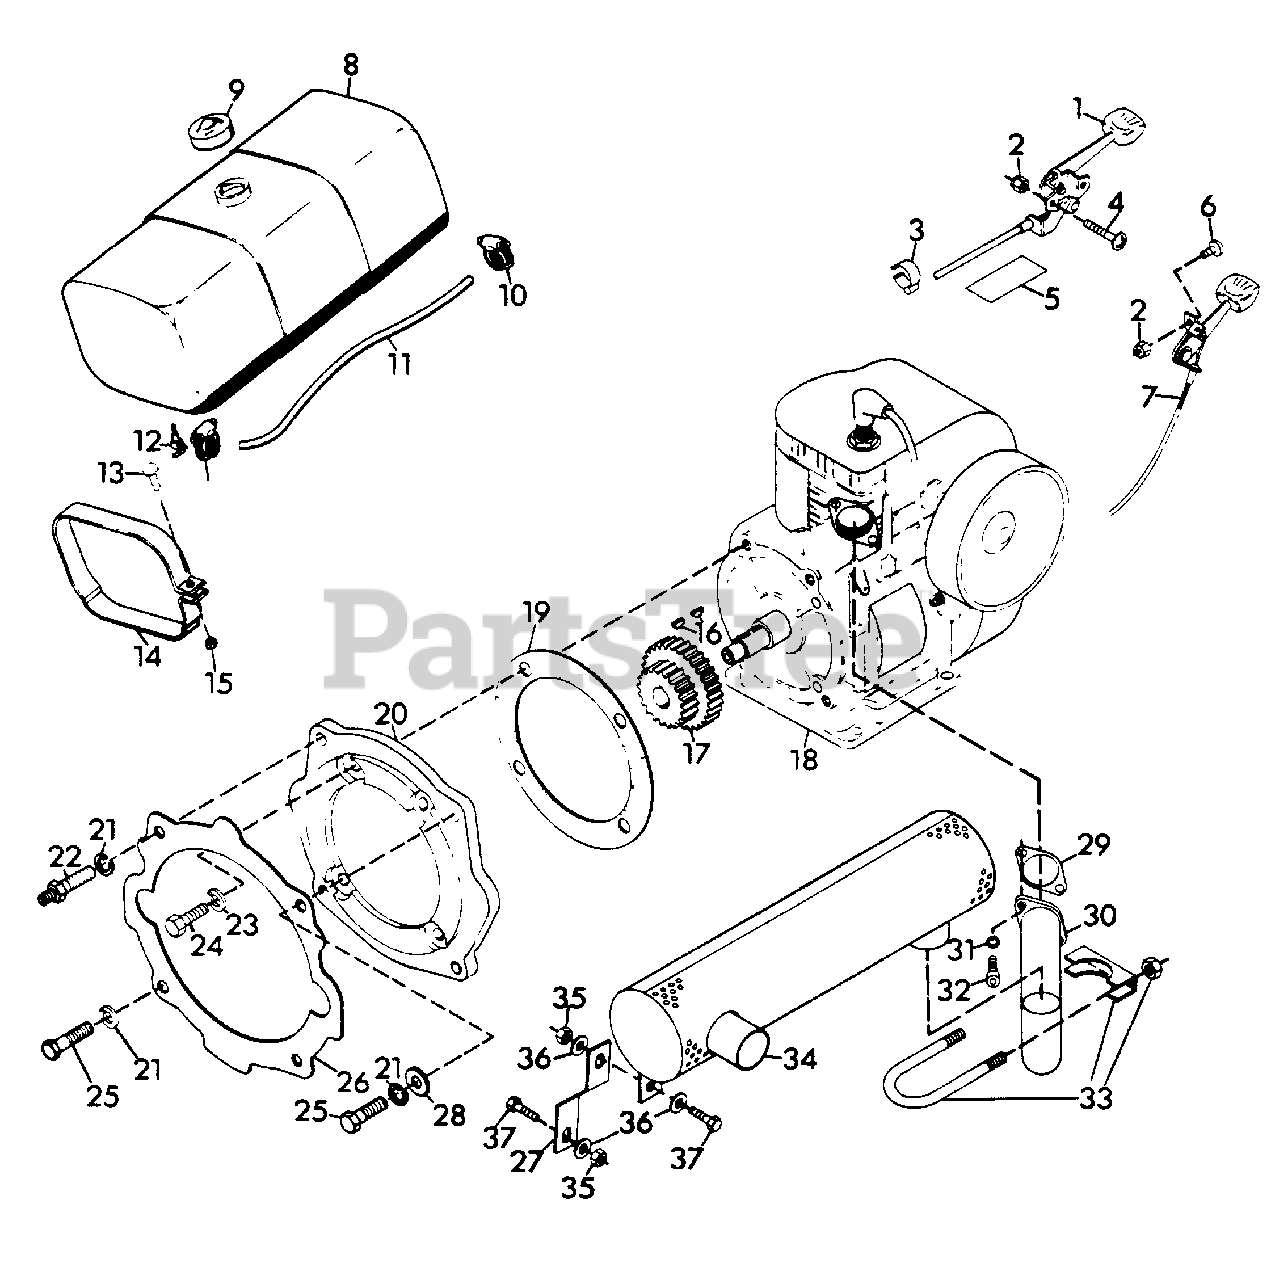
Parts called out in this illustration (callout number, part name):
1	LEVER, THROTTLE CONTROL
2	NUT, LOCK 10-24
3	CLIP, CONDUIT
4	SCREW, MACH. 10-24X1.50 PHD
5	DECAL, THROTTLE
6	SCREW, MACH. 10-24X.50 PHD
7	LEVER, CHOKE CONTROL
8	ASSEMBLY, FUEL TANK
9	CAP, GAS TANK
10	CLAMP, HOSE
11	LINE, FUEL
12	VALVE AND STRAINER
13	BOLT, 1/4-20X1.75 RD.HD.SQ. NECK
14	STRAP, FUEL TANK
15	NUT, LOCK 1/4-20
16	KEY, WOODRUFF 5/32X5/8 HARD #6
17	GEAR, 10/12 DP 21/30 TEETH
18	ENGINE, 16 H.P.
19	GASKET, ENGINE TO ADAPTOR
20	ADAPTOR, ENGINE
21	WASHER, LOCK 7/16 SP HEAVY
22	STUD
23	WASHER, LOCK 3/8 SP HEAVY
24	BOLT, HEX 3/8-16X1
25	BOLT, HEX 7/16-14X1.25
26	GASKET, CHASSIS TO ADAPTOR
27	BRACE
28	WASHER, FLAT .469X.938X.065
29	GASKET
30	HEADER, EXHAUST
31	WASHER, LOCK 5/16 REG.
32	SCREW, CAP 5/16-18X.75 SHD
33	CLAMP, MUFFLER
34	MUFFLER, 16 H.P.
35	NUT, HEX 1/4-20
36	WASHER, FLAT .312X.734X.065
37	BOLT, HEX 1/4-20X.75
